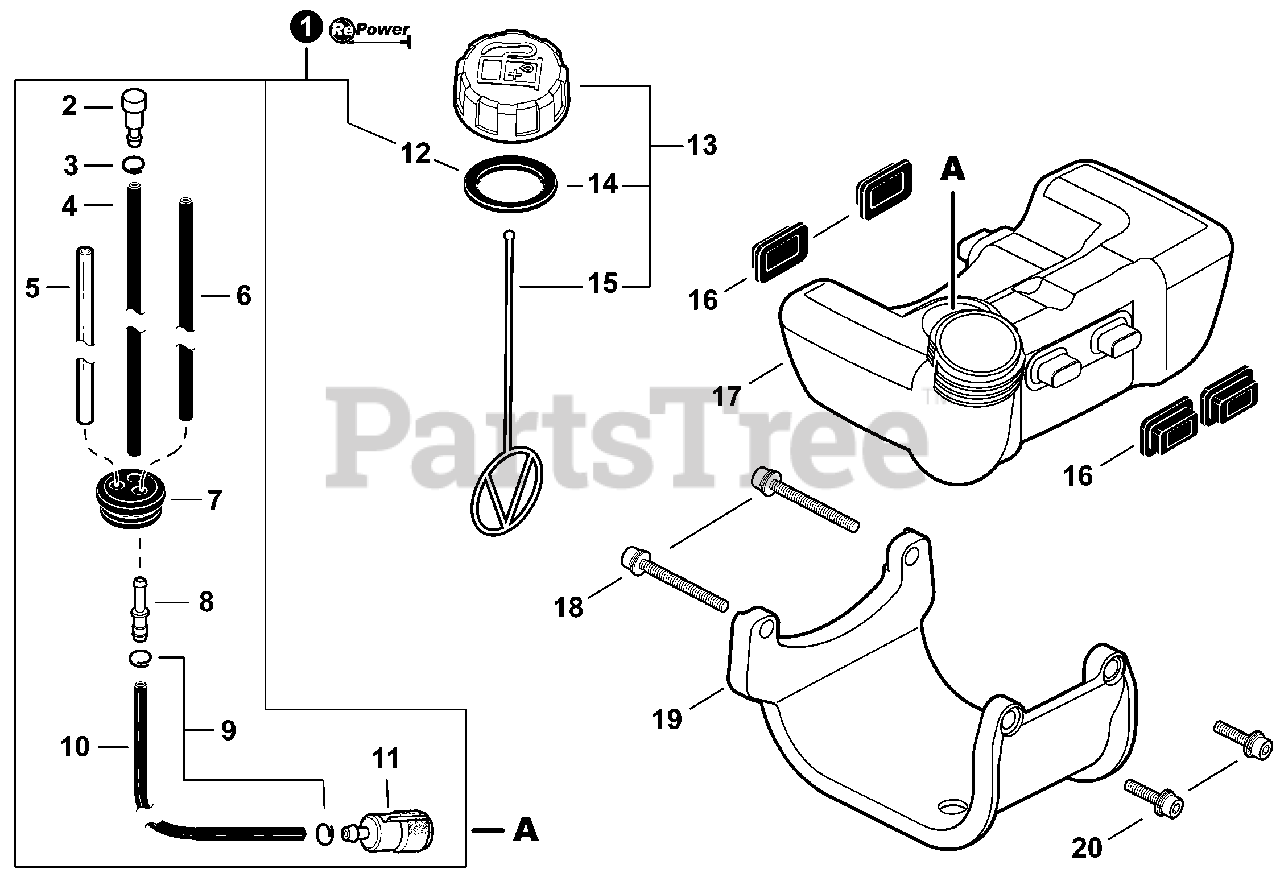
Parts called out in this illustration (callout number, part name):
1	FUEL SYSTEM KIT
2	VENT ASSY
3	CLIP Ø6.5 MM
4	PIPE, FUEL 3×6×105 BLACK
5	PIPE, FUEL 3×6×85 CLEAR
6	PIPE, FUEL 3×5×74 BLACK
7	GROMMET, FUEL
8	CONNECTOR, PIPE Ø5ר3.5
9	CLIP Ø6
10	PIPE, FUEL 3×5×140 BLACK
11	FILTER, FUEL 125-528
12	GASKET, FUEL CAP
13	CAP ASSY, FUEL
14	GASKET, FUEL CAP
15	CONNECTOR, CAP L= 123
16	CUSHION, FUEL TANK
17	TANK, FUEL
18	BOLT 5×40
19	GUARD, FUEL TANK
20	BOLT 5×18
